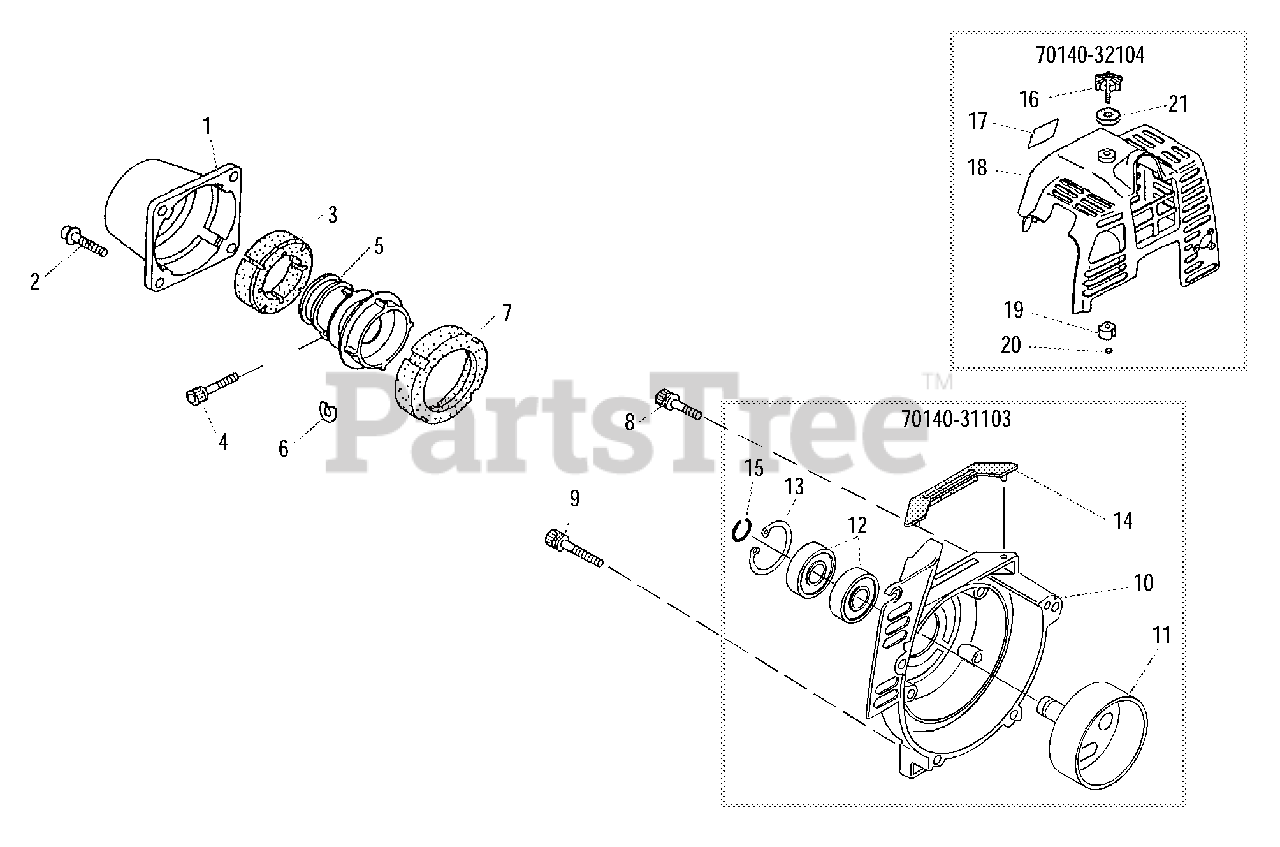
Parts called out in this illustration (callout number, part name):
1	COVER, AV CUSHION (RED)
2	BOLT M5×16
3	CUSHION, FRONT
4	BOLT M5×25
5	JOINT
6	D-WASHER
7	HOLDER, REAR CUSHION
8	BOLT M5×16
9	BOLT M5×35
10	COVER, FAN
11	DRUM, CLUTCH
12	BEARING, BALL 6000ZZ
13	RING, SNAP Ø26
14	CUSHION
15	RING, SNAP WR10
16	THUMBSCREW
17	LABEL
18	COVER, ENGINE
19	INSULATOR 5 MM
20	CLIP
21	WASHER, CONE M6
70140-31103	COVER ASSY, FAN
70140-32104	ENGINE COVER KIT - RED
